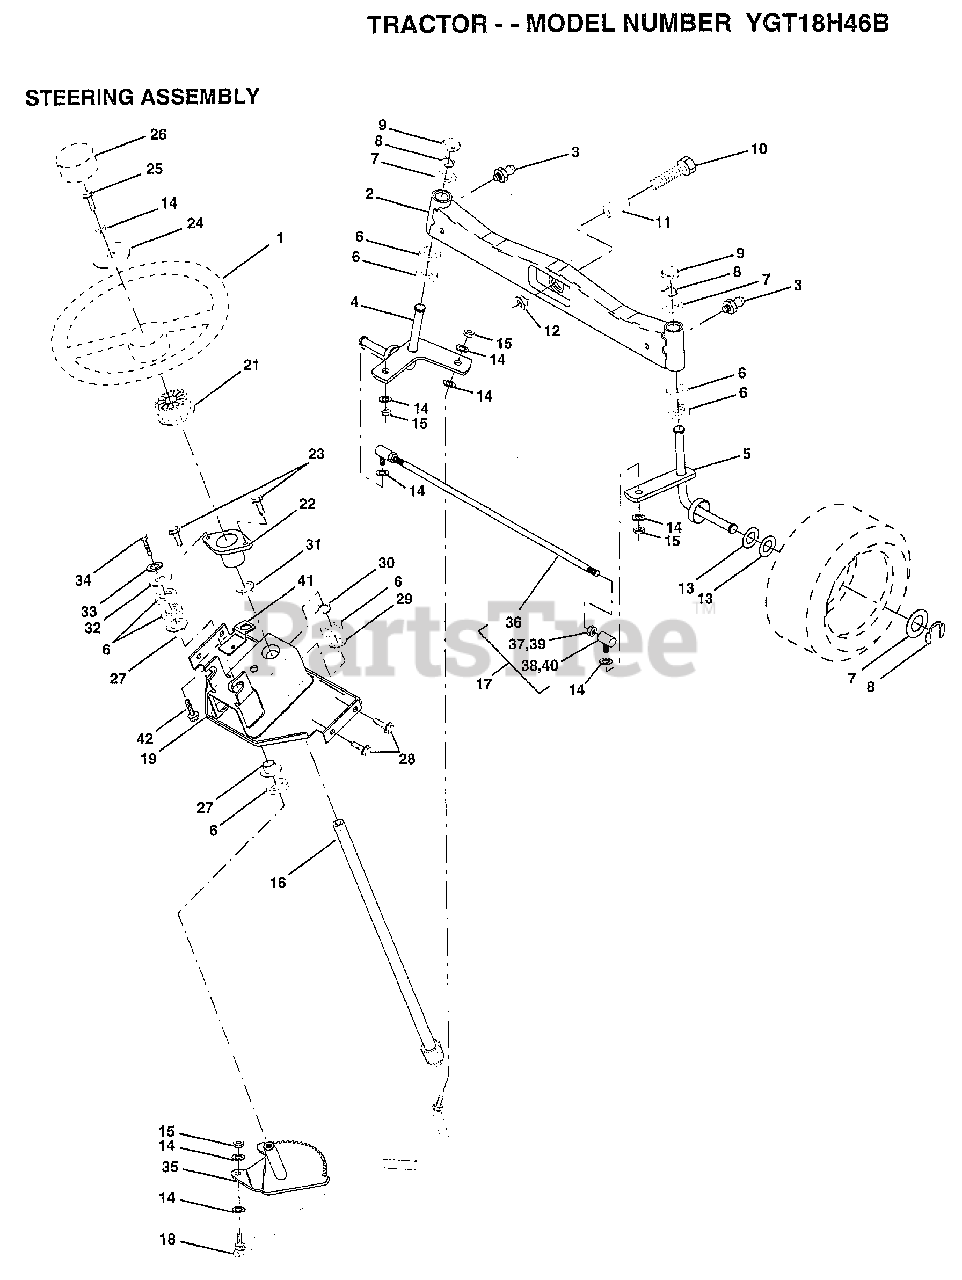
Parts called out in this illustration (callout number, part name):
3	ZERK M
4	SPINDLE ASM LH
5	SPINDLE ASM RH
6	WASHER .T
7	WASHER
8	RING
9	CAP
10	BOLT
11	SPACER BEARING
12	"NUT-LOC,FLANGE LT"
14	LOCKWASHER
15	GRIPCO NUT
16	SHAFT.STEER.VGT
17	ROD.ASM.TIE.BALL
18	DRAGLINK.BALL.JOI
19	SUPPORT ASM-STEER
21	ADAPTER LT
22	"BUSHING,STEERING"
23	"SCREW-TT,10-32 FL"
24	WASHER T
25	BOLT
26	"INSERT,STR WHEEL"
27	COL. SRTG. BEAR.
28	SCREW
29	"FLANGE GT, BEAR."
30	KLIP RING
31	BUSHING.NYLINER.
32	WASHER
33	LOCKWASHER
34	BOLT
35	GEAR.ASM.SECTOR.
37	NUT
38	JOINT.RH
39	NUT
40	JOINT.LH
41	"BRKT-SW, INTER"
42	SCREW LT
